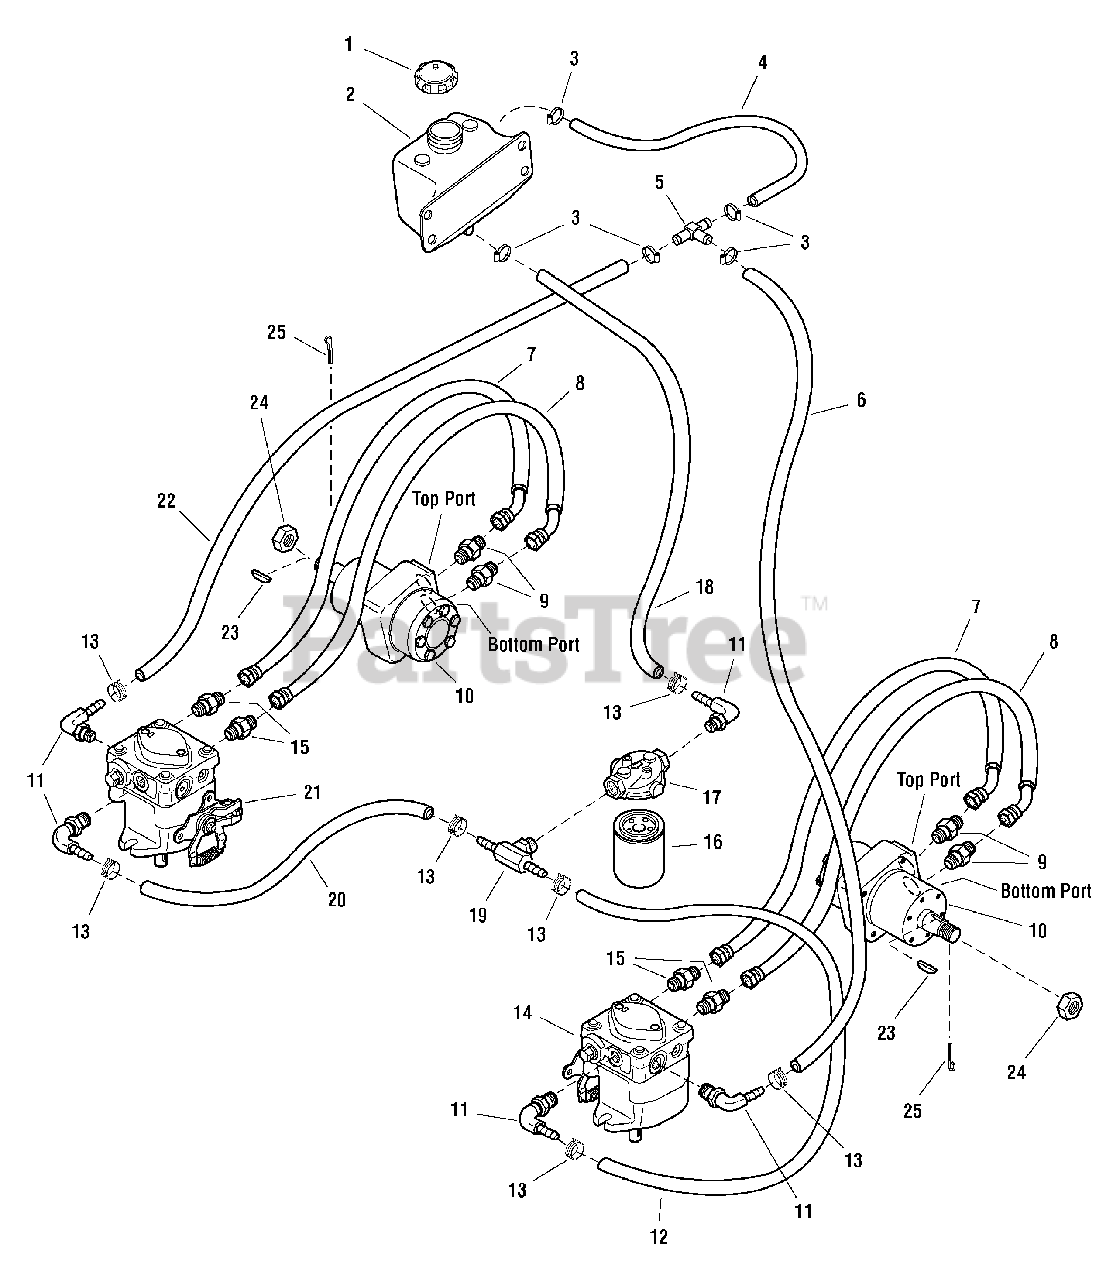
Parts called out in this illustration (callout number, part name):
2	HYDRAULIC TANK
3	CLAMP, #6 Hose
4	HOSE, 3/8 X 6-1/2" LONG
5	FITTING, Tee
6	HOSE, 3/8 X 25-1/2" LONG
7	HOSE ASSEMBLY, Hi Press, 25-1/2"
8	HOSE ASSEMBLY, Hi Press, 29"
9	FITTING, Adapter
10	WHEEL MOTOR
11	FITTING, 90 DEG. O-Ring
12	HOSE, 3/8 X 17" LONG
13	CLAMP, Hose
14	HYDRAULIC PUMP, LH
15	FITTING, Adapter
16	FILTER
17	FILTER, Head
18	HOSE, 3/8 X 13" LONG
19	FITTING, Tee
20	HOSE, 3/8 X 8-3/4" LONG
21	HYDRAULIC PUMP, RH
22	HOSE, 3/8 X 7-1/2" LONG
23	KEY
24	NUT, Castle
25	PIN, Cotter, 1/8 X 1-1/4
